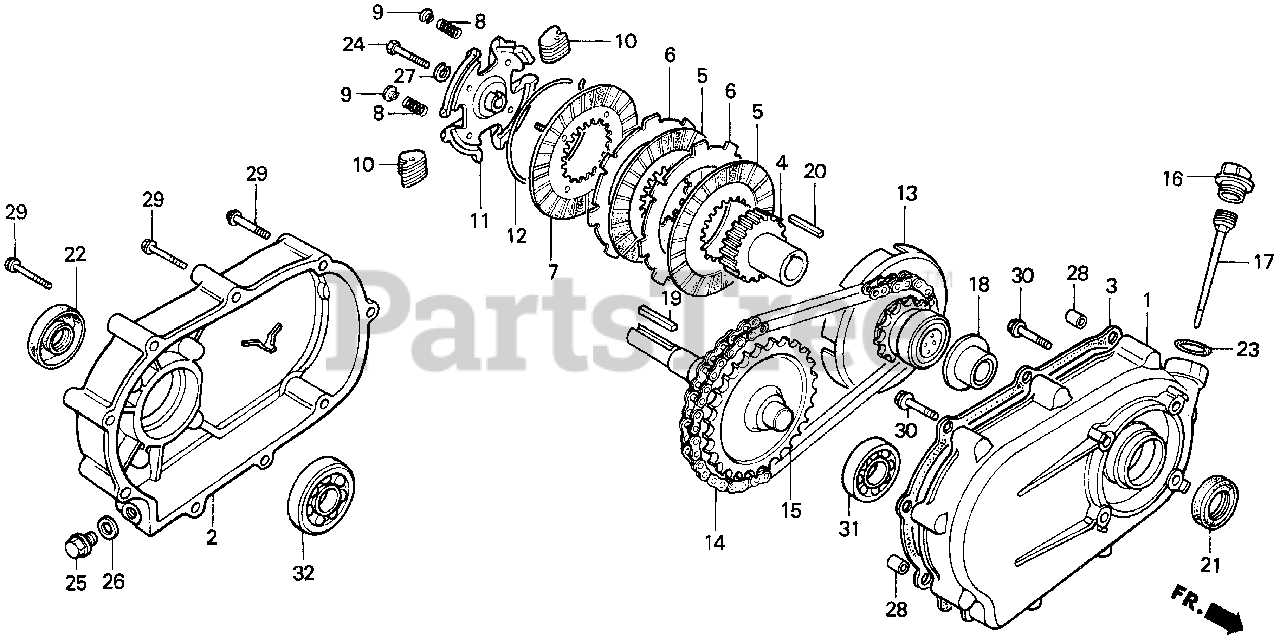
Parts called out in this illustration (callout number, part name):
1	CASE, REDUCTION
2	COVER, REDUCTION
3	GASKET, REDUCTION COVER
4	CENTER, CLUTCH
5	DISK, CLUTCH FRICTION
6	PLATE, CLUTCH
7	PLATE, CLUTCH PRESSURE
8	SPRING, CLUTCH FREE
9	HOLDER, CLUTCH SPRING
10	WEIGHT, CLUTCH
11	HOLDER, CLUTCH WEIGHT
12	CENTER, CLUTCH WEIGHT
13	SPROCKET, DRIVE (14T)
14	CHAIN, DRIVE (RK428SH-36LE)
15	SHAFT, P.T.O. (28T)
16	CAP, REDUCTION OIL
17	DIPSTICK, OIL
18	WASHER, THRUST (25MM)
19	KEY (7X7X33)
20	KEY, CLUTCH CENTER
21	OIL SEAL (30X46X8)
22	OIL SEAL (PJ30507)
23	O-RING (26X2.7)
24	BOLT, HEX. (8X35)
25	BOLT, DRAIN PLUG (12MM)
26	WASHER, DRAIN PLUG (12MM)
27	WASHER, SPRING (8MM)
28	PIN A, DOWEL (8X14)
29	BOLT, FLANGE (6X50)
30	BOLT, FLANGE (8X32)
31	BEARING, RADIAL BALL (6205)
32	BEARING, RADIAL BALL (6206)
